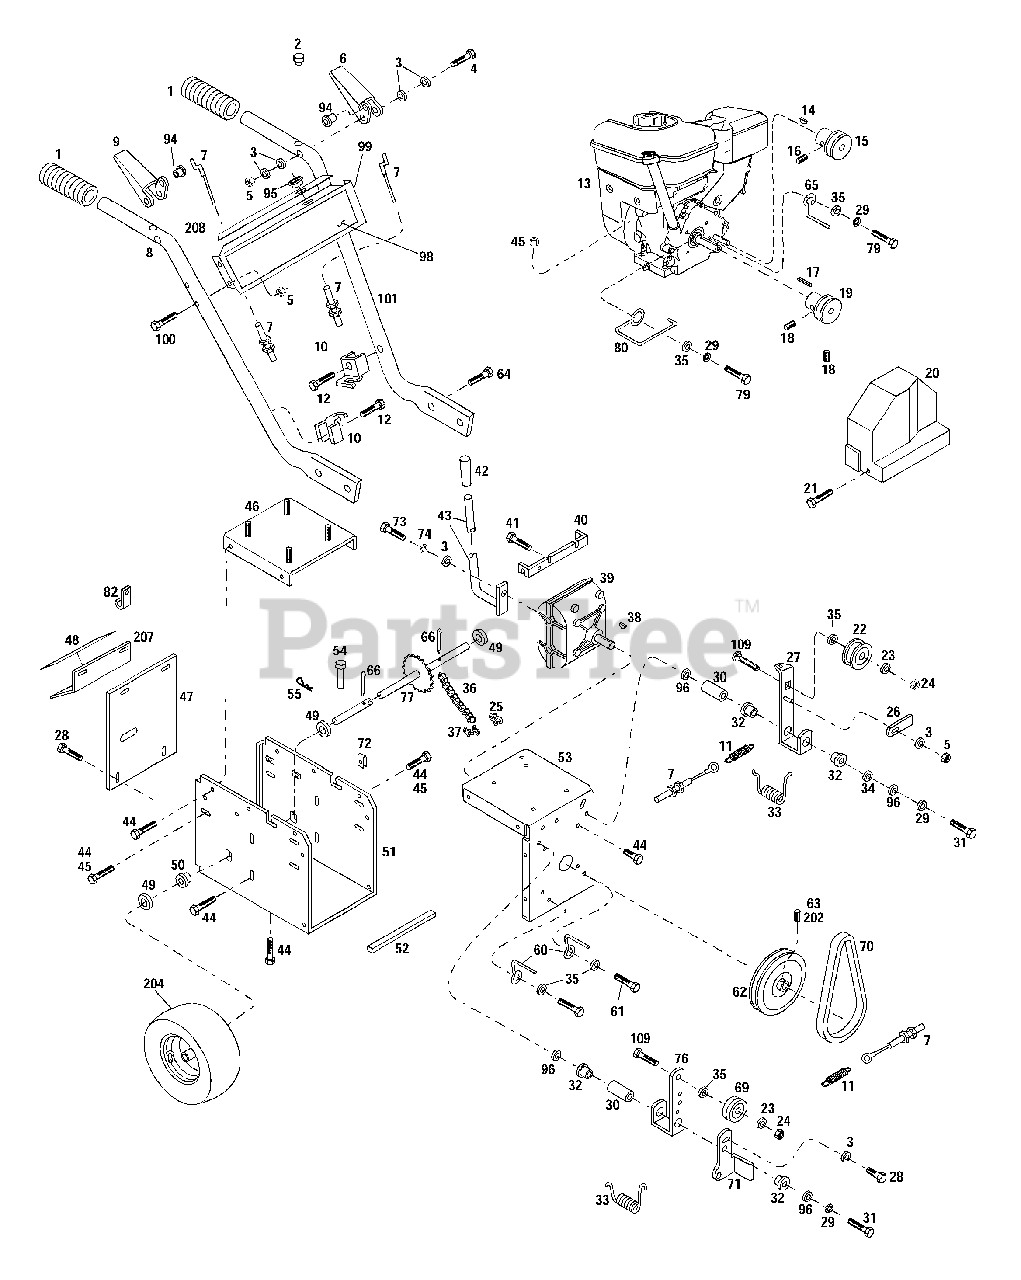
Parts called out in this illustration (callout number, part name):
1	Handle Grip
2	Bumper
3	Flat Washer, 1/4
4	Hex hd. Screw, 1/4-20 x 1-3/4
5	Locknut, 1/4-20
6	Control Lever
7	Drive Cable
8	Handlebar - right hand
9	Control Lever
10	Cable Bracket
11	Extension Spring
12	Thread Forming Screw, 1/4-20 x 3/4
13	Engine
14	Woodruff Key, 1/8 x 5/8
15	PTO Sheave
16	Set Screw, 1/4-20 x 3/8
17	Square Key, 3/16 x 3/4
18	Set Screw, 5/16-18 x 5/16
19	Engine Sheave
20	Belt Cover
21	Truss Screw, #10-24 x 5/8
22	Idler Pulley
23	Lockwasher, 3/8
24	Hex Nut, 3/8-16
25	Link-Offset
26	Idler Arm Stop
27	Idler Arm
28	Thread Forming Screw, 1/4-20 x 1/2
29	Lockwasher, 5/16
30	Spacer
31	Hex hd. Screw, 5/16-18 x 2-1/2
32	Bearing - Nyliner
33	Torsion Spring
34	Flat Washer, 1/2
35	Flat Washer, 5/16
36	Drive Chain #41
37	Connector Link
38	Hi-Pro Key, 3/16 x 3/4
39	Transmission
40	Reinforcement Bracket
41	Thread Forming Screw, 5/16-18 x 3/4
42	Handle Grip
43	Shift Handle
44	Hex Hd. Flange Screw, 5/16-18 x 1/2
45	Flange Locknut, 5/16-18
46	Doubler Plate Assembly
47	Rear Cover
48	Shift Decal
49	Flat Washer
52	Rubber Pad
53	Frame Cover
54	Clevis Pin
60	Belt Guide
61	Hex hd. Screw, 5/16-18 x 3/4
62	Transmission Sheave
63	Set Screw, 5/16-18 x 5/8
64	Hex Flange Screw, 5/16-18 x 5/8
65	Belt Guide
66	Cotter Pin, 1/8 x 1-1/4
69	Flat Idler
70	V-Belt
71	Brake Arm
72	Speed Nut, #10
73	Hex hd. Screw, 1/4-28 x 3/4
74	Lockwasher, 1/4
76	Idler Arm
79	Hex hd. Screw, 5/16-24 x 3/4
80	Belt Guide
82	Cable Clamp
94	Nyliner Bearing
95	Grommet
96	Flat Washer, 1/4
98	Decal, Logo - Model 42046
99	Console
100	Hex hd. Screw, 1/4-20 x 1-1/2
101	Handlebar - left hand
109	Carriage Bolt, 3/8-16 x 1-3/4
202	Loctite #242, .02 oz.
204	Wheel and Tire Assembly
207	Bracket, Shift Decal
208	Decal, Instructions
